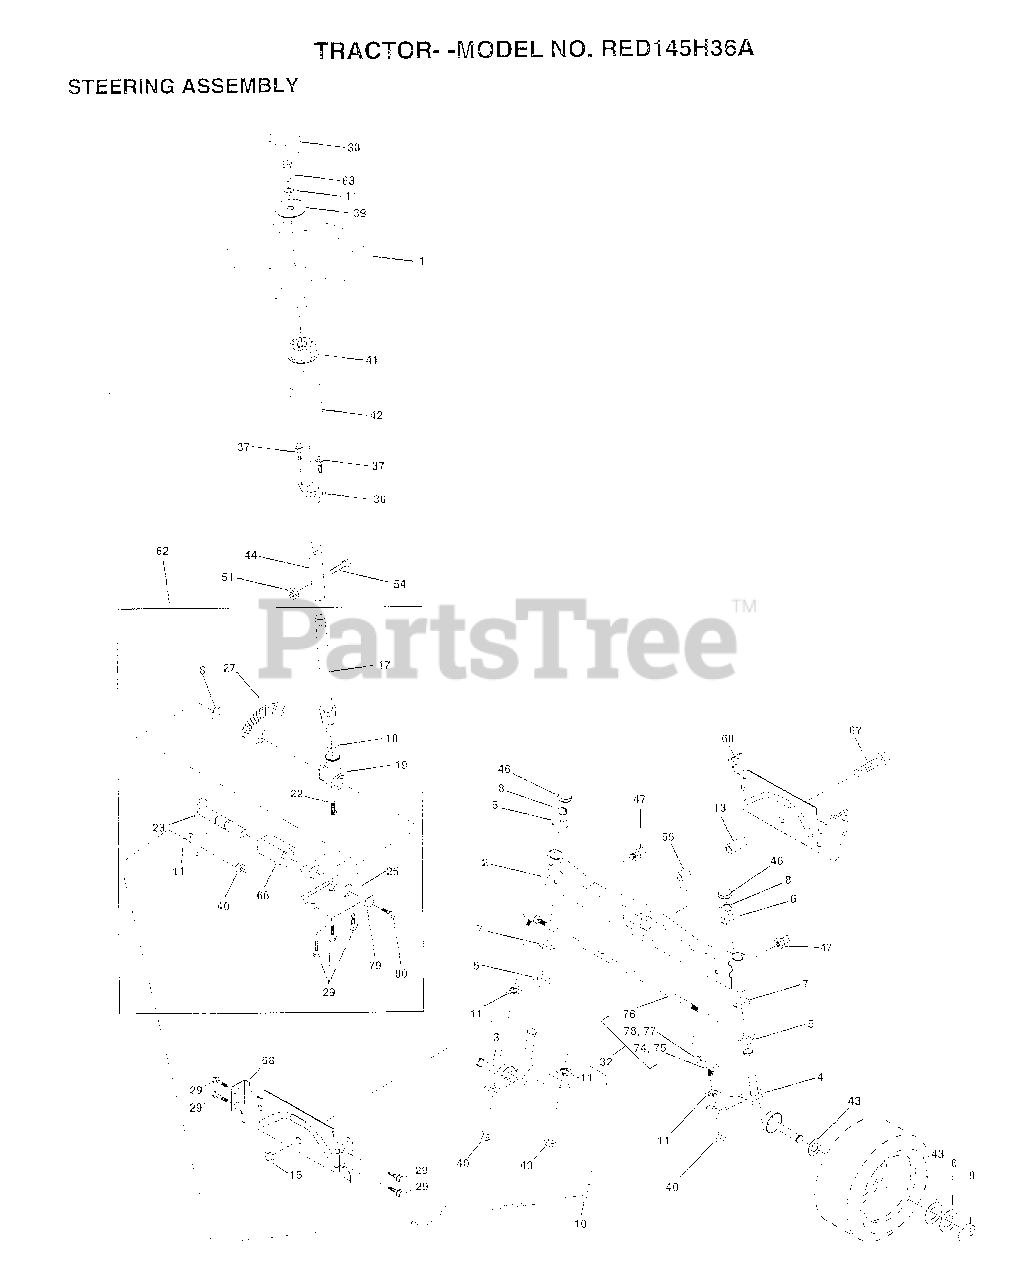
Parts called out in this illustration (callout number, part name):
3	"SPINDLE ASM,LH"
4	"SPINDLE ASM,RH"
5	WASHER .T
6	WASHER
7	WASHER
8	RING
10	LINK.DRAG
11	LOCKWASHER
13	BEARING.FRT.SPACER.AXLE
15	"NUT-LOC,FLANGE LT"
17	SHAFT ASM STEERIN
18	THRUST WASHER
19	SUPPORT.SHAFT.STEER
22	SCREW.HX.WSH.HD
23	SHAFT.ASM.PITMAN
25	BRKT-STEERING
27	GEAR SECTOR
29	SCREW
32	ROD.ASM.TIE.BALL
36	BUSHING.STEERING
37	"SCREW-TT,10-32 FL"
38	ST WHL INSERT CAP
39	WASHER T
40	GRIPCO NUT
41	ADAPTER LT
42	BOOT.STEER.PL
43	WASHER
44	EXT SHAFT STEERIN
46	CAP
47	ZERK M
51	NUT
54	BOLT
62	KIT.STEER.ASM
63	BOLT
65	SPACER AXLE
66	"BEARING-ARM,PITMA"
67	BOLT
68	BRACE AXLE
74	JOINT.RH
75	JOINT.LH
77	NUT
78	NUT
79	WASHER
80	BOLT.HX.NYLON3/8-16X3/
81	SCREW.HXWSH.3/8
